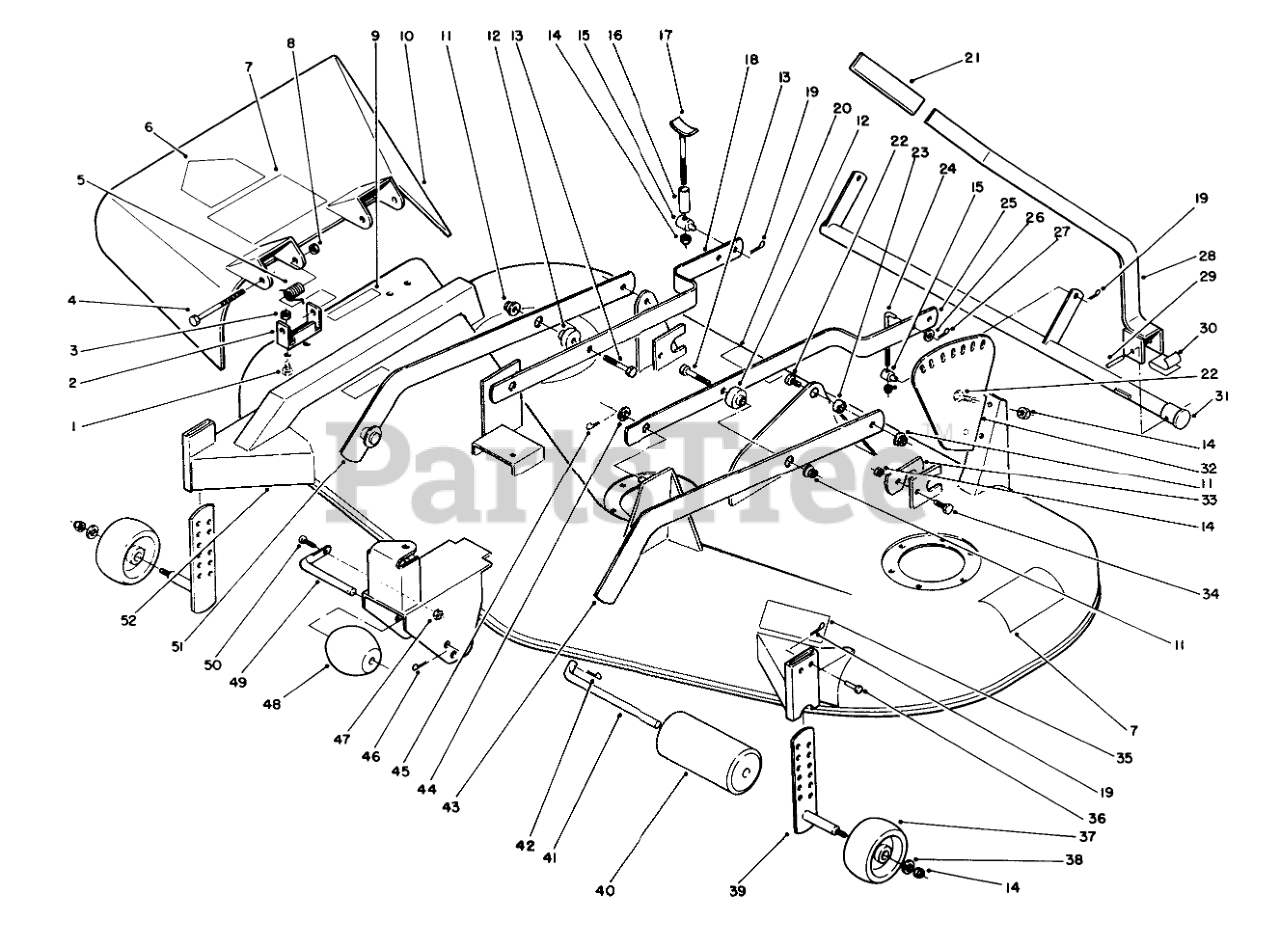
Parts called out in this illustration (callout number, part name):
1	Bolt Carnage
2	Bracket-Pivot
3	Nut
4	SCREW-HH
5	SPRING
6	DECAL-DANGER
7	DECAL-DANGER, THROWN OBJECT
8	NUT-HEX
9	DECAL-DANGER
10	Deflector Assembly (Incl. Ref. #6 & 7)
11	LOCKNUT-FLANGE
12	SPACER
13	Bolt
14	NUT
15	TRUNNION
16	SPACER .375 ID X 1.6
17	WLDMT-HANGER ROD
18	Bar-Leveler
19	Hairpin Cotter
20	DECAL-BELT ROUTING
22	Bolt
23	SPACER
24	ROD-LIFT
25	Draft Bar RH
26	WASHER 5/16 SAE
27	Cotter Pin
28	Lever
29	SPIROL PIN
30	CLIP-SPRING
31	Lit Arm Assembly
32	Quadrant
33	LOCK-SHAFT
34	Bolt
35	TUBE ASM
36	PIN-CLEVIS
37	WHEEL-GAGE
38	WASHER-FLAT
39	Plate
40	ROLLER-DECK
41	SHAFT-ROLLER, REAR
43	Draft Bar LH
44	WASHER
45	PIN-4
46	Cotter Pin
47	Nut
48	ROLLER
49	SHAFT-ROLLER
50	Bolt
51	Draft Bar RH
52	Deck Assembly
